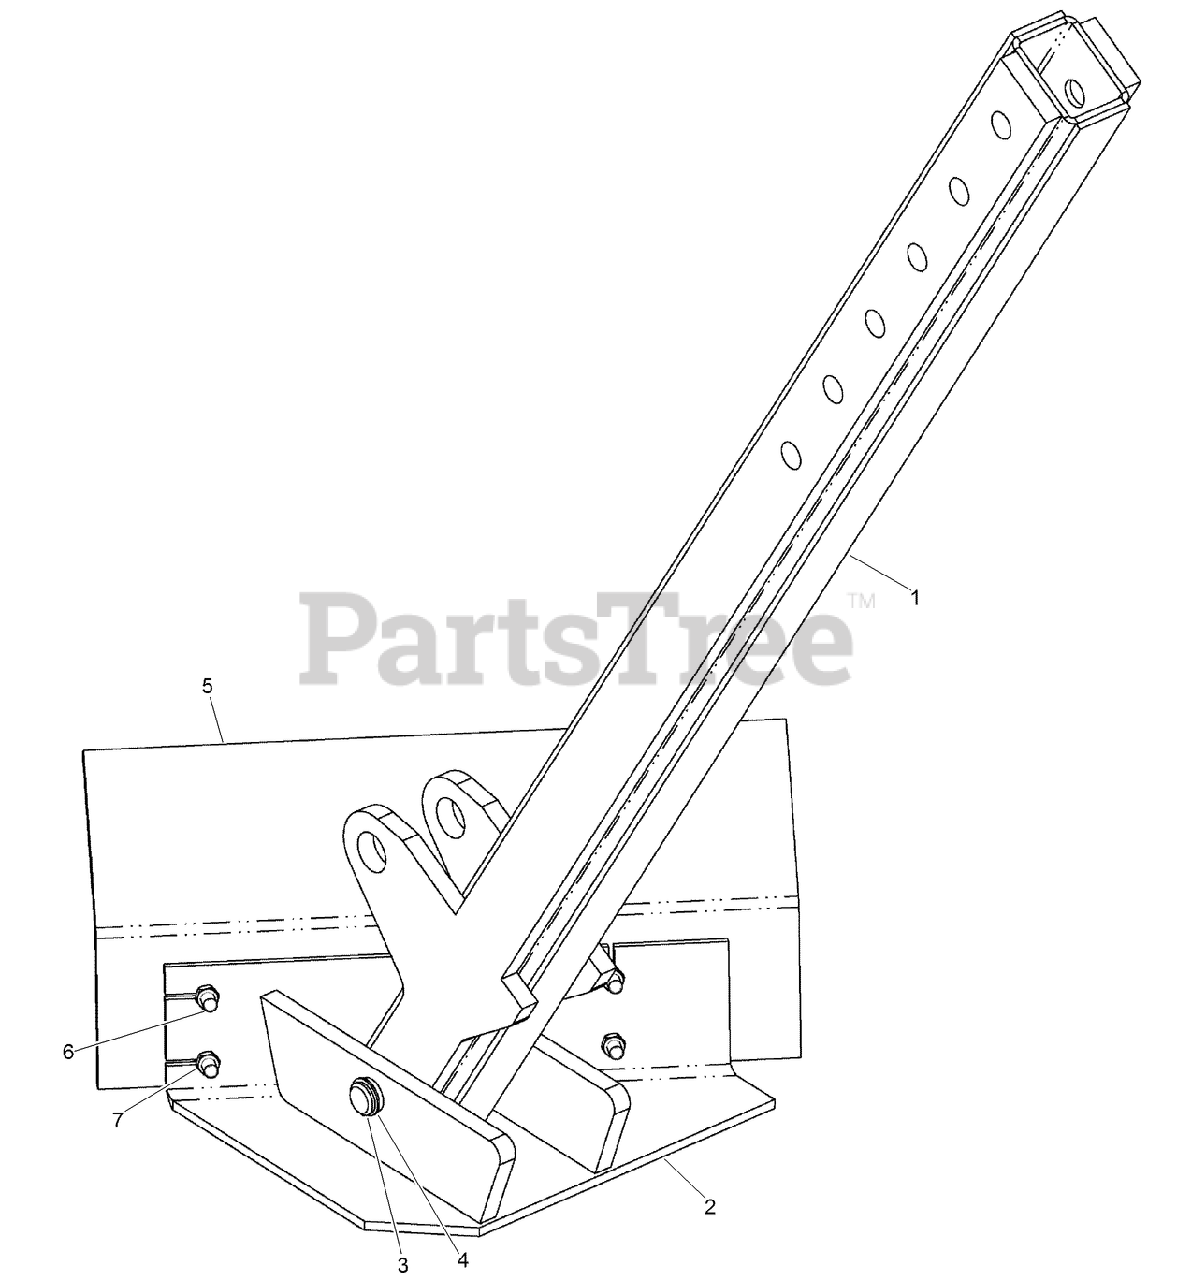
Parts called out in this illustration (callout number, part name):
1	WELDMENT - Stabilizer Bar
2	WELDMENT - Foot, Right-Hand
3	PIN-PIVOT
4	RING-RETAINING
5	PLATE - Berm Scraper
7	NUT-LOCK, HEX
